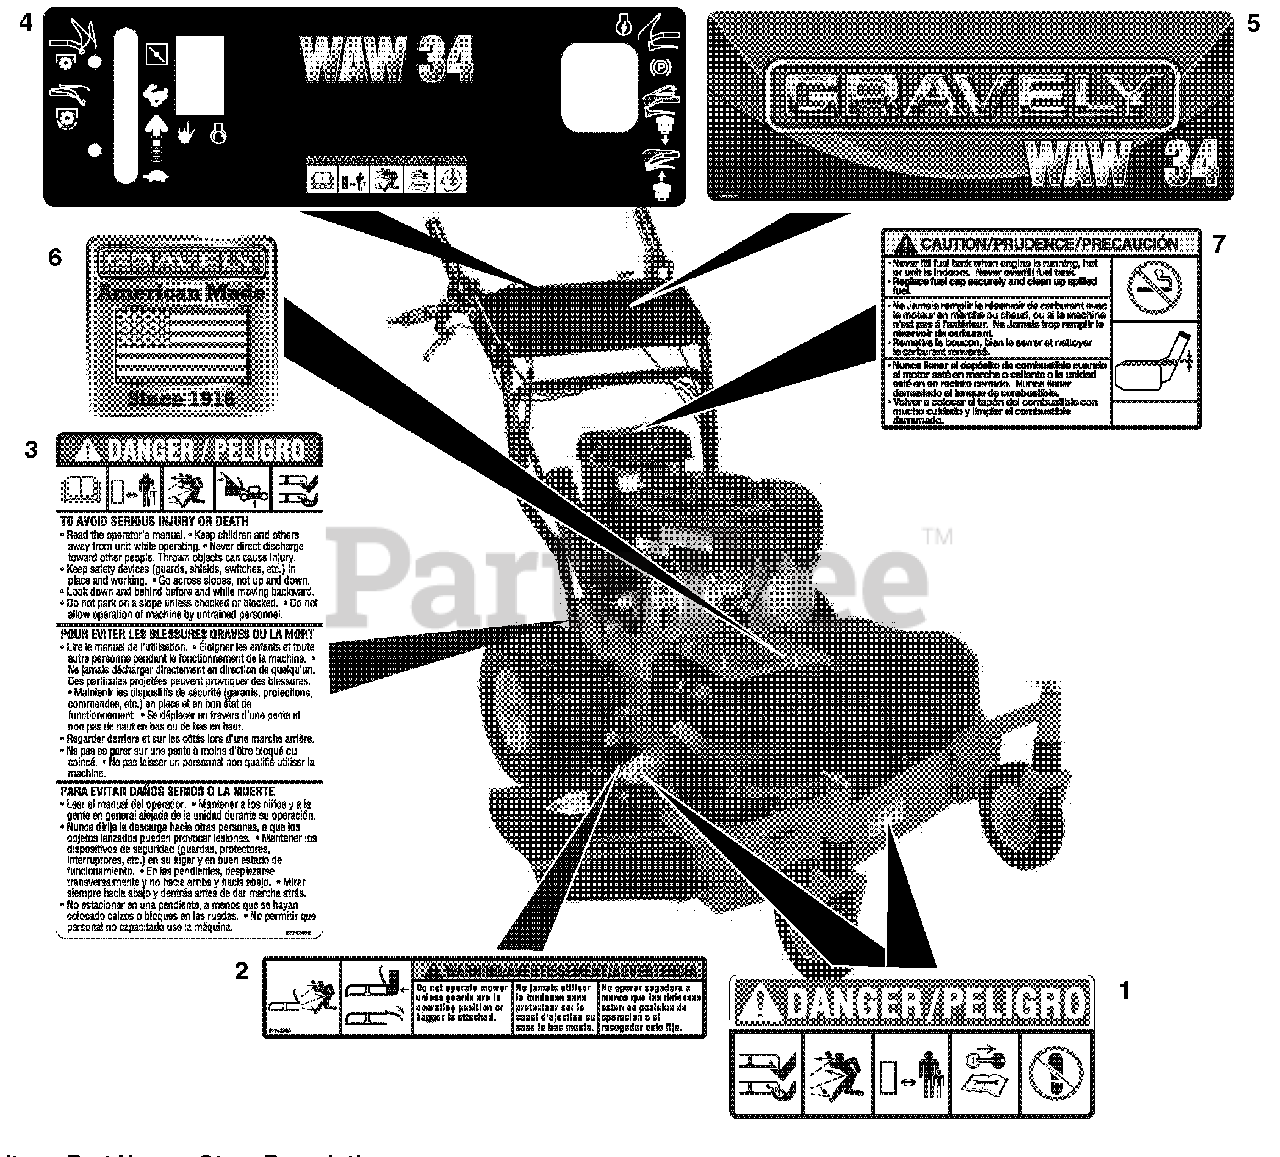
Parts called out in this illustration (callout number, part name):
1	Decal, Mower Pan Head Danger
2	Decal, Warning
3	Decal, Bilingual Danger
4	Decal, WAW 34 Operational
5	Decal, WAW 34 Gravely Dash
6	Decal, Made In America
7	Decal, Fuel, Warning
